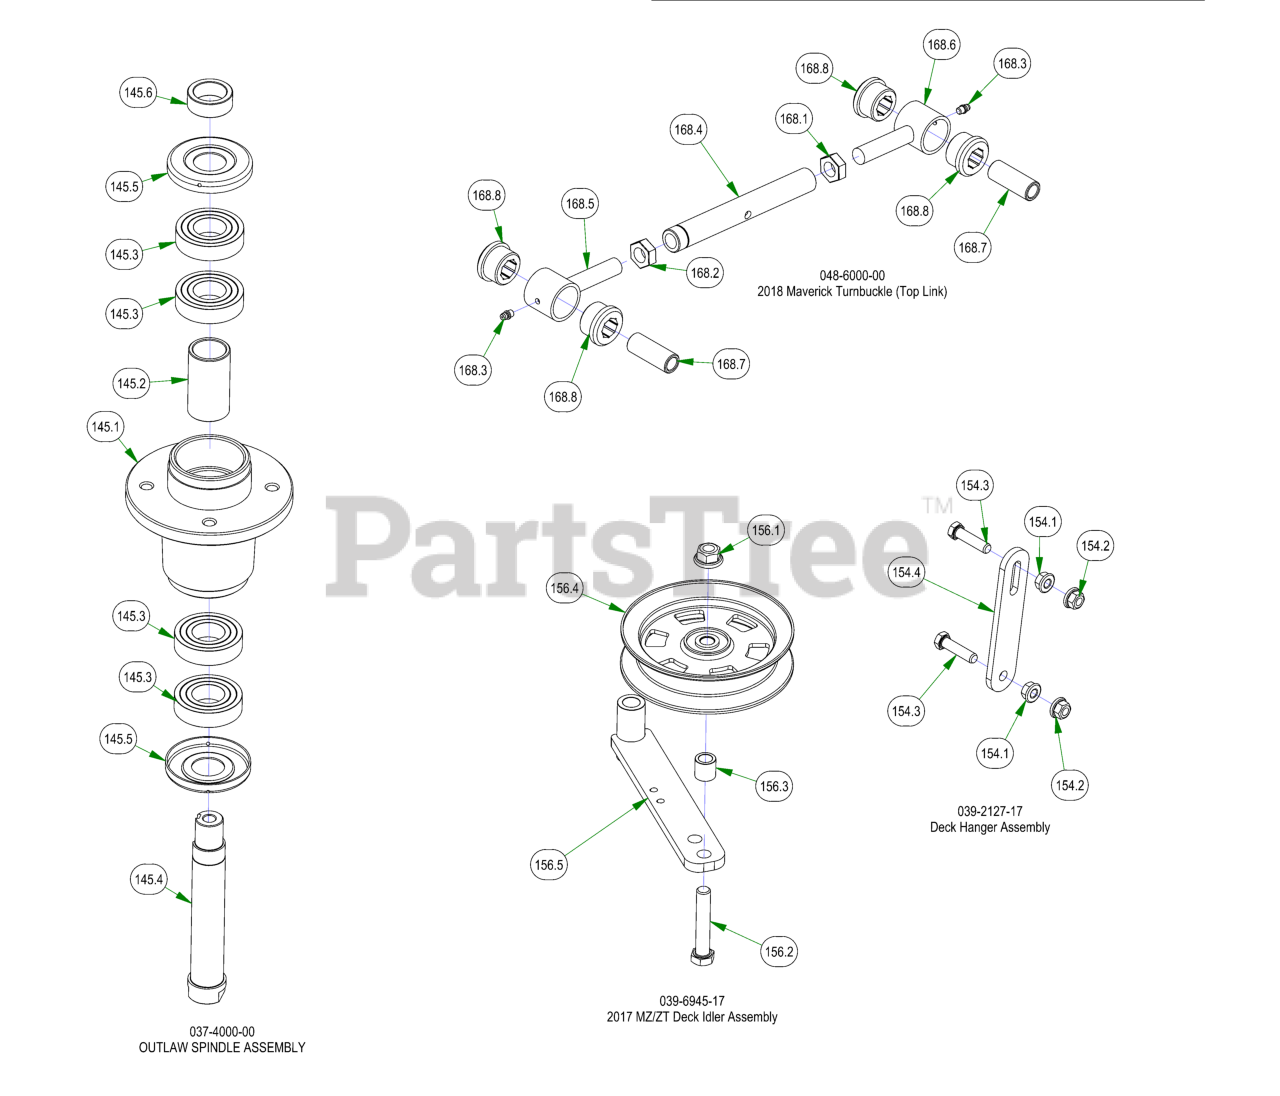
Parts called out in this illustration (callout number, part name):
59	5/16-18 X 1-1/4 CARRIAGE BOLT ZINC
108	2023 4" & 5" Stripping Kit Plate
145	OUTLAW SPINDLE ASSEMBLY
145.1	4000 Series Spindle Housing
145.2	4000 Series Spindle Spacer
145.3	Bearing - 6206
145.4	Spindle Shaft
145.5	Spindle Dust Cap
145.6	Locking Collar w/ 1/4"-20 Set Screw
154	Deck Hanger Assembly
154.1	3/8-16 HEX SERRATED FLANGE NUT HARD/ZINC
154.2	3/8-16 NYLON INSERT FLANGE LOCKNUT (GR.F) ZINC
154.3	3/8-16 X 1-1/2 HEX CAP SCREW (GR.5) ZINC
154.4	2017 MZ/ZT Deck Hanger
156	2017 MZ/ZT Deck Idler Assembly
156.1	1/2-13 NYLON INSERT FLANGE LOCKNUT ZINC
156.2	1/2-13 X 2-3/4 HEX CAP SCREW (GR.5) ZINC
156.3	Spacer 3/4 OD x 1/2 ID x 3\4 Length
156.4	5" Idler Pully
156.5	Deck Idler
168	2018 Maverick Turnbuckle (Top Link)
168.1	NUT, 5/8-18
168.2	NUT, 5/8-18LH
168.3	1/4-28 Grease Fitting
168.4	2018 Maverick Toplink Body
168.5	2018 Maverick Bushing Retainer Left-Handed
168.6	2018 Maverick Bushing Retainer Right-Handed
168.7	2018 Maverick Bushing Sleeve
168.8	2018 Maverick Bushing
202	2023 ZT Stripping Kit Rubber
